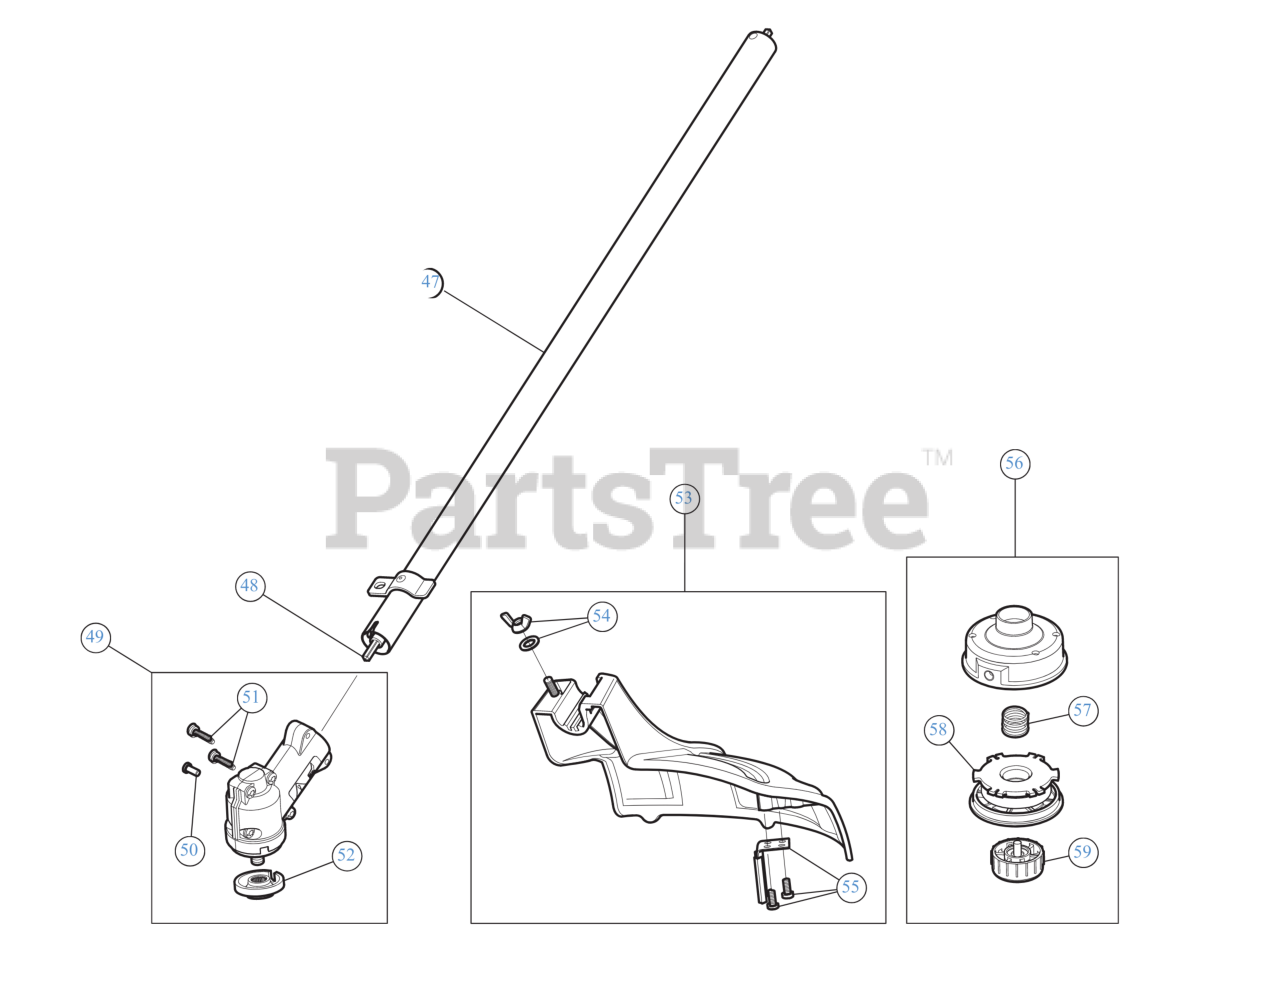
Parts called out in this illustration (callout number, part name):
47	LOWER SHAFT HOUSING
48	LOWER DRIVE SHAFT
49	GEARBOX LCBC
50	SCREW, 8-32 x .312 P
52	CUTTING HEAD SPACER
53	GUARD/BLADE ASM
54	BLADE GUARD MOUNTING HARDWARE
55	BLADE ASSEMBLY W/HDW
56	BUMPHEAD
57	SPRING-SPOOL
58	INNER REEL W/LINE (LH)
59	BUMP KNOB (BLACK)
